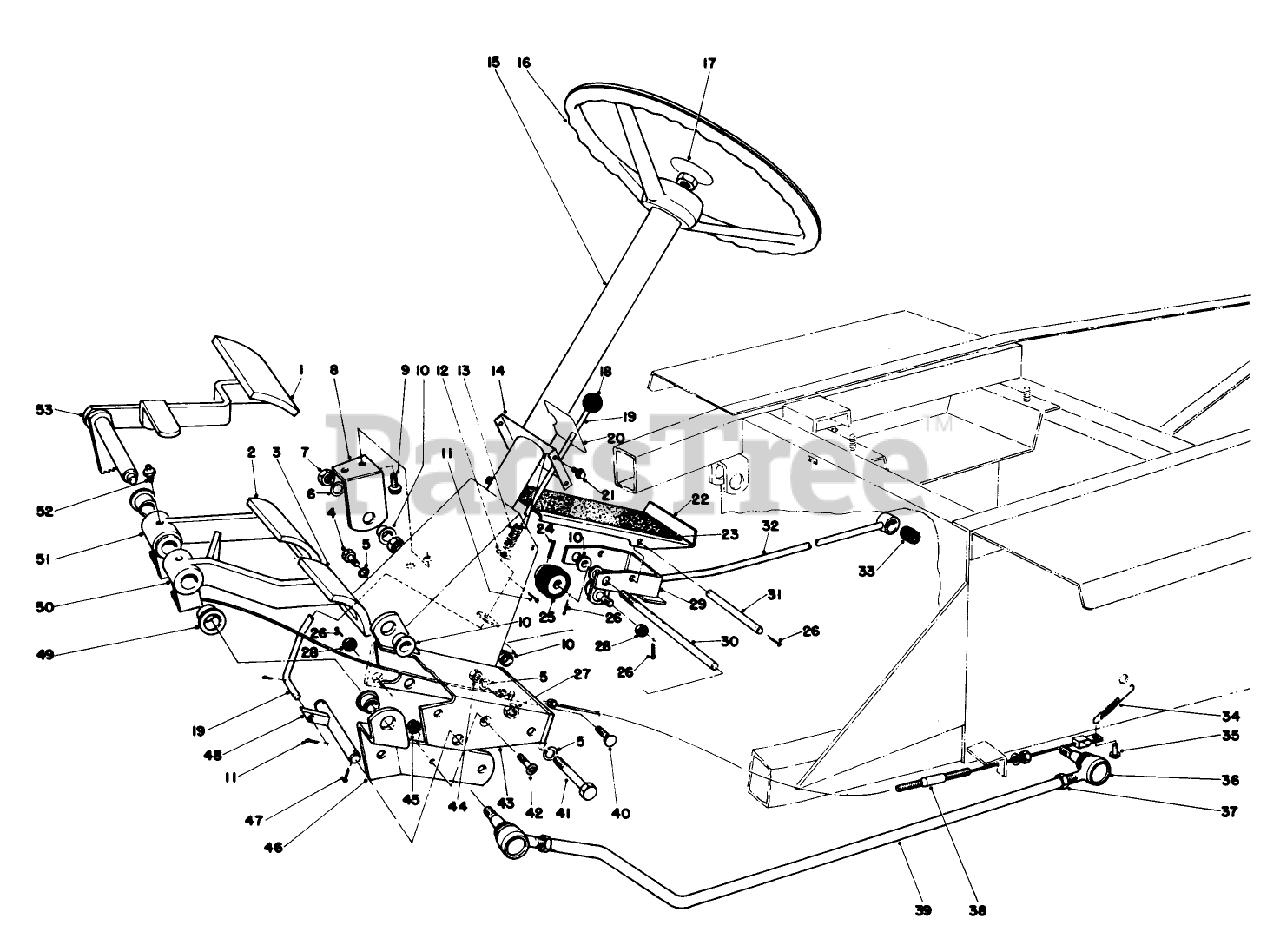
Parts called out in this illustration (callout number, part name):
1	PAD-BRAKE
2	PAD-TURN, RIGHT
3	PAD-TURN, LEFT
4	SCREW-HH
5	WASHER-LOCK
6	WASHER-FLAT
7	NUT-JAM
8	Mount-RH Pedal
9	SCREW-HWHTF
10	BUSHING-FLANGE
11	PIN-COTTER
12	WASHER-FLAT
13	Spring
14	STRG COLUMN SUPT R
15	STEERING GEAR ASM,GM72 PRE 1988
16	STEERING WHEEL
17	STEERING WHEEL CAP
19	BRAKE LATCH ROD B
20	PARKING BRAKE DECAL
21	SCREW-HWH
22	TRACTION PEDAL R
23	TRACTION PEDAL PAD
24	PIN-SPRING
25	FRICTION WHEEL ASM
26	PIN-COTTER
27	NUT-HEX
28	NUT-SLOTTED
29	Pivot Bracket (Incl. Ref. #10)
30	TRACT PEDAL SHAFT
31	TRACT PEDAL PIN
32	PUMP CONTROL TUBE WA
33	BUSHING-RUBBER
34	SPRING-EXTENSION
35	PIN-CLEVIS
36	Socket
37	NUT-JAM
38	LH BRAKE CABLE ASM
39	Tube Front Steering
40	SCREW-CARR
41	SCREW-HH
42	SCREW-HSFH
43	Brake Mount
44	NUT-HEX
45	NUT-KEPS
46	Brake Pivot Shaft Mount
47	PIN-COTTER
48	Brake Latch Shaft
49	BUSHING-FLANGE
50	Brake Pedal L.H. (Incl. Ref. #49)
51	Brake Pedal R.H. (Incl. Ref. #49)
52	FITTING-GREASE
53	Pedal-Parking Bake
